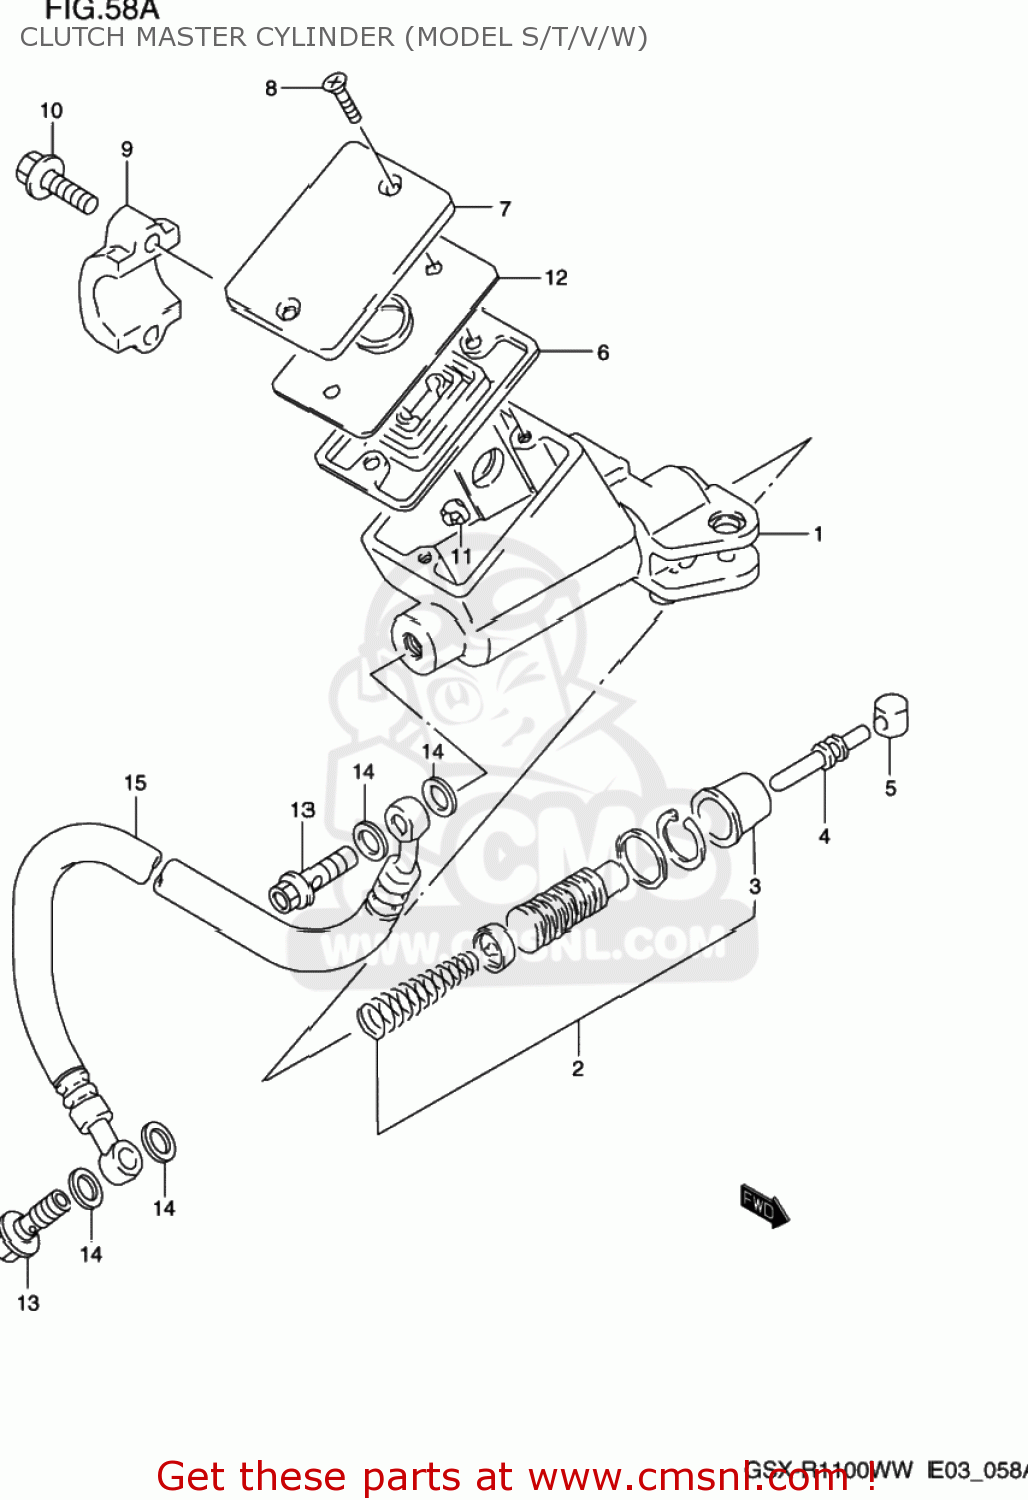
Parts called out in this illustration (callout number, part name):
1	CYLINDER ASSY,CLUTCH MASTER
2	PISTON & CUP SET
3	BOOT
4	ROD,PUSH
5	BUSH
6	7
7	CAP
8	SCREW
9	HOLDER
10	BOLT(6X25)
11	PROTECTOR
12	PLATE,DIAPHRAGM
13	BOLT UNION
14	WASHER(10X15X1.5)
15	HOSE COMP,CLUTCH
